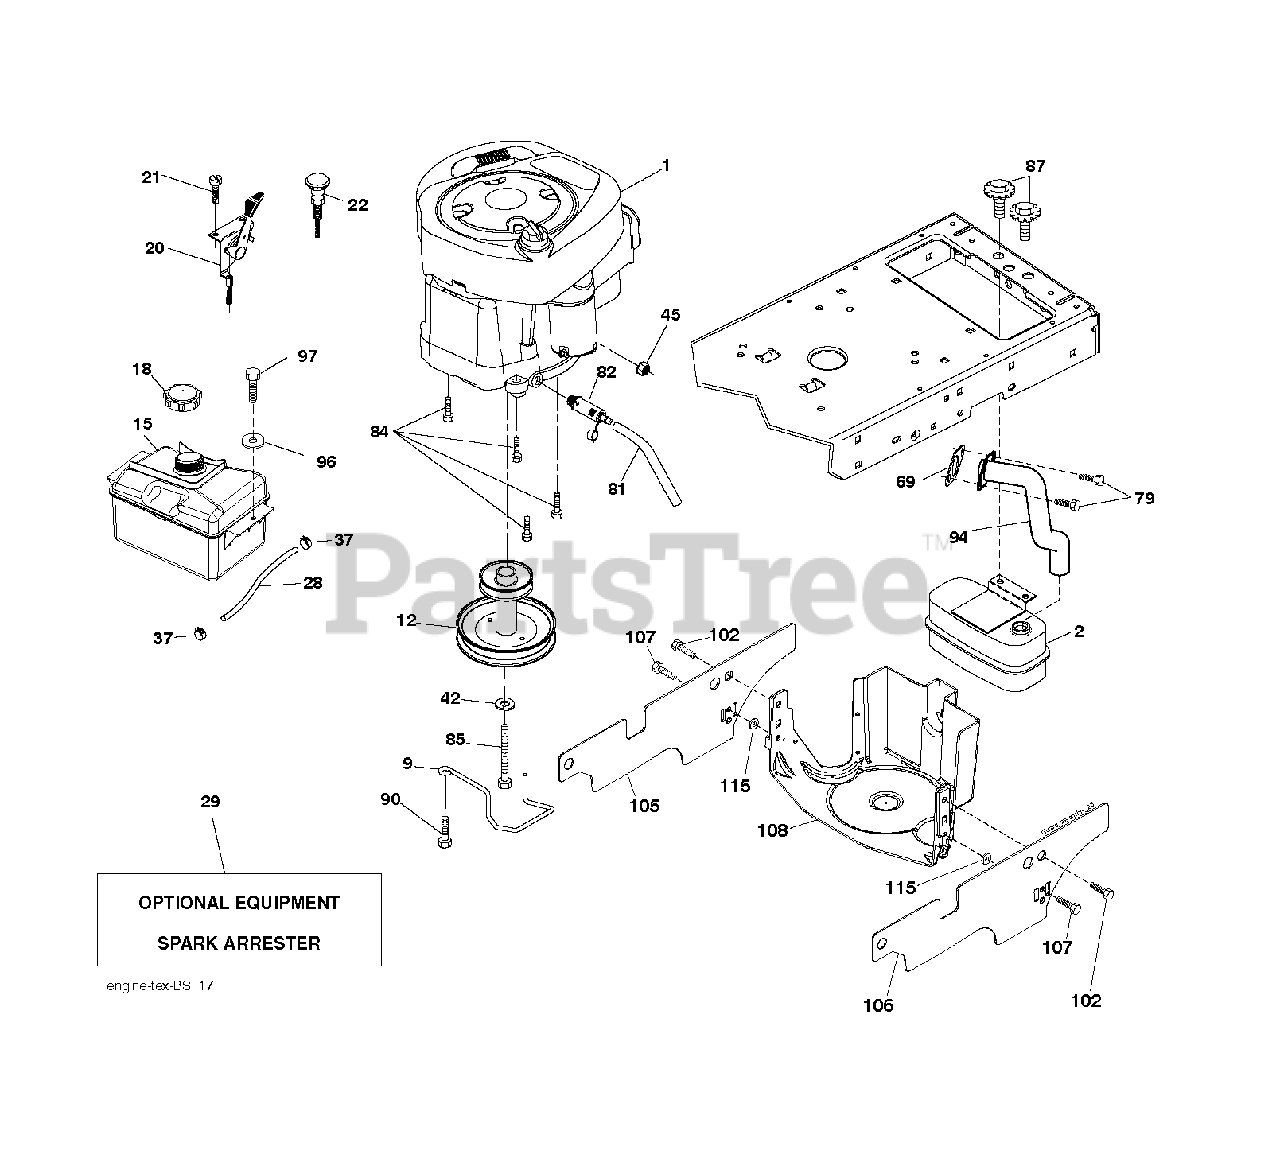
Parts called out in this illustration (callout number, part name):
2	MUFFLER.SINGLE.CYL.KOHL/B&S
9	KEEPER.BELT.ENGINE.3.25
12	PULLEY ENGINE
15	TANK FUEL FRT 1.5 GAL
18	FUEL CAP
20	CONTROL.TH/CK.C.
21	SCREW.#10 X 0.750.BOS THREAD
28	LINE.FUEL.20
29	ARRESTER SPARK (OPTIONAL)
37	HOSE CLAMP
42	LOCKWASHER
45	NUT
69	REPL BY 532 27 22-93
79	SCREW.SOCKET HD.5/16-1
81	TUBE, DRAIN OIL ASM.
82	PLUG DRAIN OIL EASY
84	SCREW.3/8-16
85	BOLT HEX 7/16-20X4-1/4"
87	BOLT, 5/16-18 X 1 3/4
90	SCREW 3/8-16X1
94	EXHAUST.TUBE.B&S.
97	SCREW HEXWSHR 1/4-20X3/4
102	SCREW
107	SCREW.1/4-20X5/8
115	PALNUT 1/4
